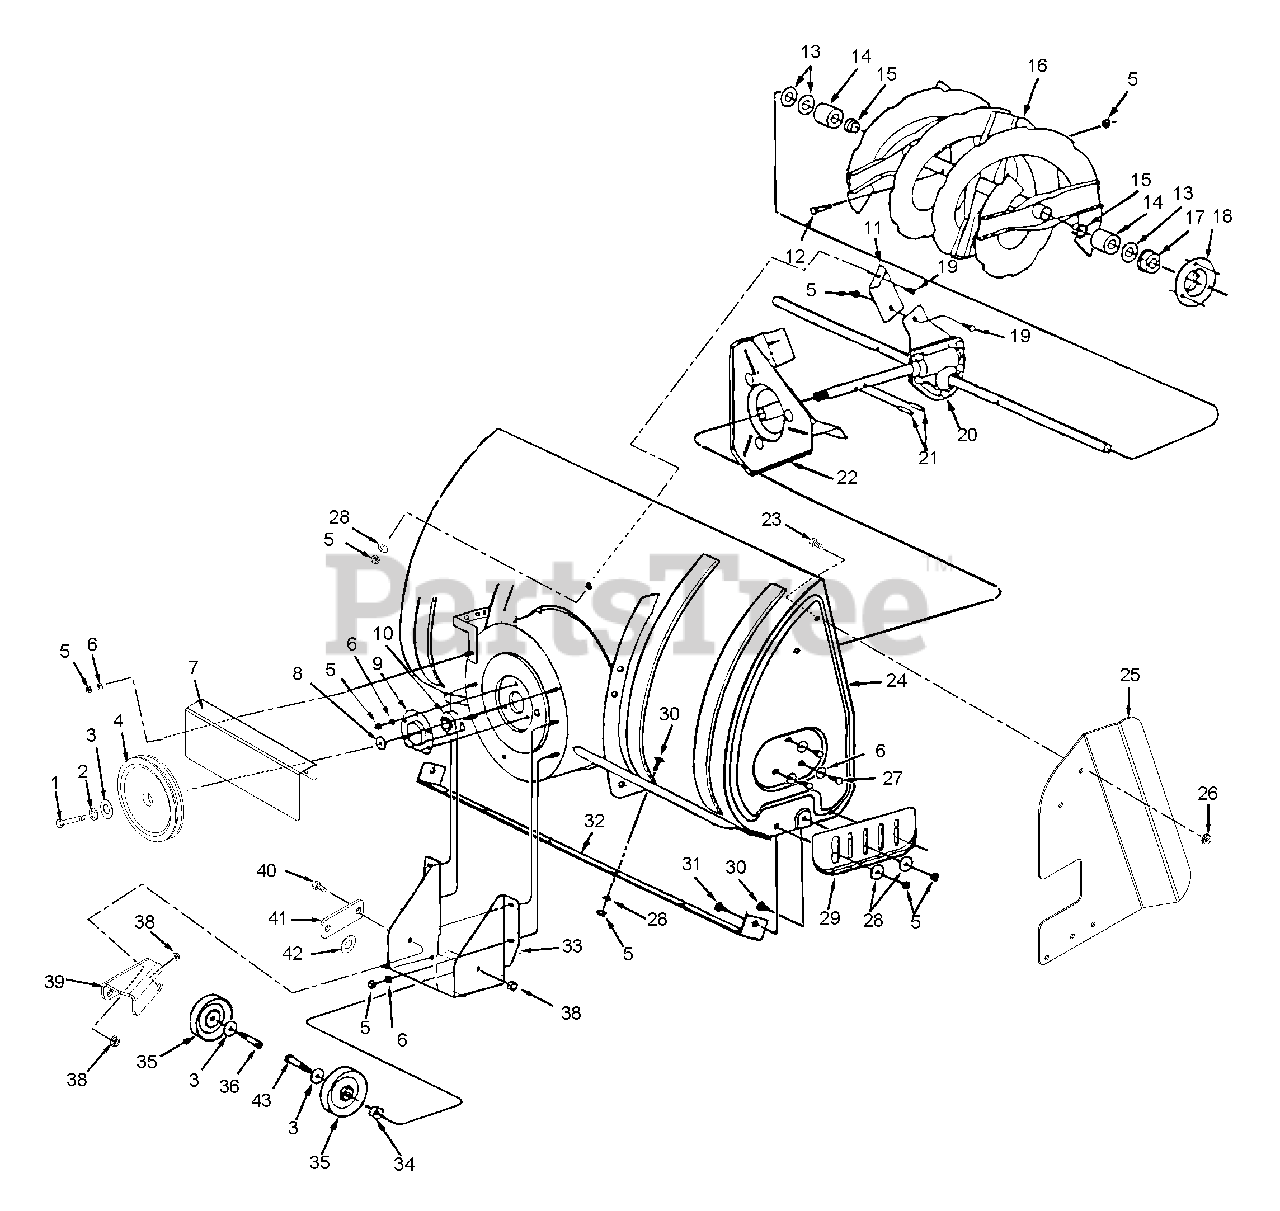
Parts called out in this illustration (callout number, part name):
1	BLT-HEX .38-24X1.0 YWZC GR5
2	@WSHR-LK .38X.094 REG YWZC
3	@WSHR-FL-STL.406X.812X.065 YWZ
4	Pulley, V-Type
5	@NUT-LK-CTR .31-18 YWZC
6	@WSHR-LK .31X.078 REG YWZC
7	GUARD,FINGER
8	Bushing
9	Housing, Bearing
10	Bearing, Ball
11	Bracket, Housing Brace
16	Spiral Assembly, R.H.
16	Spiral Assembly, L. H.
17	Bearing Flange
18	Housing, Bearing
19	@BLT-HEX .31-18X.75 GR5 YWZC
20	Gear Assembly
22	Impeller Assembly
23	@BLT-RDHDSQNK .31-18X.75 G5YZ
24	Housing Assembly
25	DRIFT-CUTTER RH
25	DRIFT-CUTTER LH
26	@NUT-LK-TOP-FLG .31-18 YWZC
27	@SCR-TAP .31-18X.75 HWH TR YWZ
28	@WSHR-FL-STL.344X.688X.065YWZC
29	Skid Shoe
30	@BLT-RDHDSQNK .31-18X.75 G5YZ
31	@BLT-RDHDSQNK .31-18X1.00 G5YZ
32	Scraper Plate
33	Bracket, Idler
34	BSHG-SLV .391X.688X.52 PM
35	IDLER-V 4.00 X .38 NWHAMSHR
36	@BLT-HEX .38-16X1.50 GR5 YWZC
37	Spacer
38	@NUT-LK-TOP-FLG .38-16 YWZC
39	BKT,IDLER SHEAVE
40	@BLT-HEX .38-16X1.00 GR5 YWZC
41	PLATE,SHIM
42	WSHR-FL-STL .406X1.00X.188 YWZ
43	@BLT-HEX .38-16X2.00 GR5 YWZC
